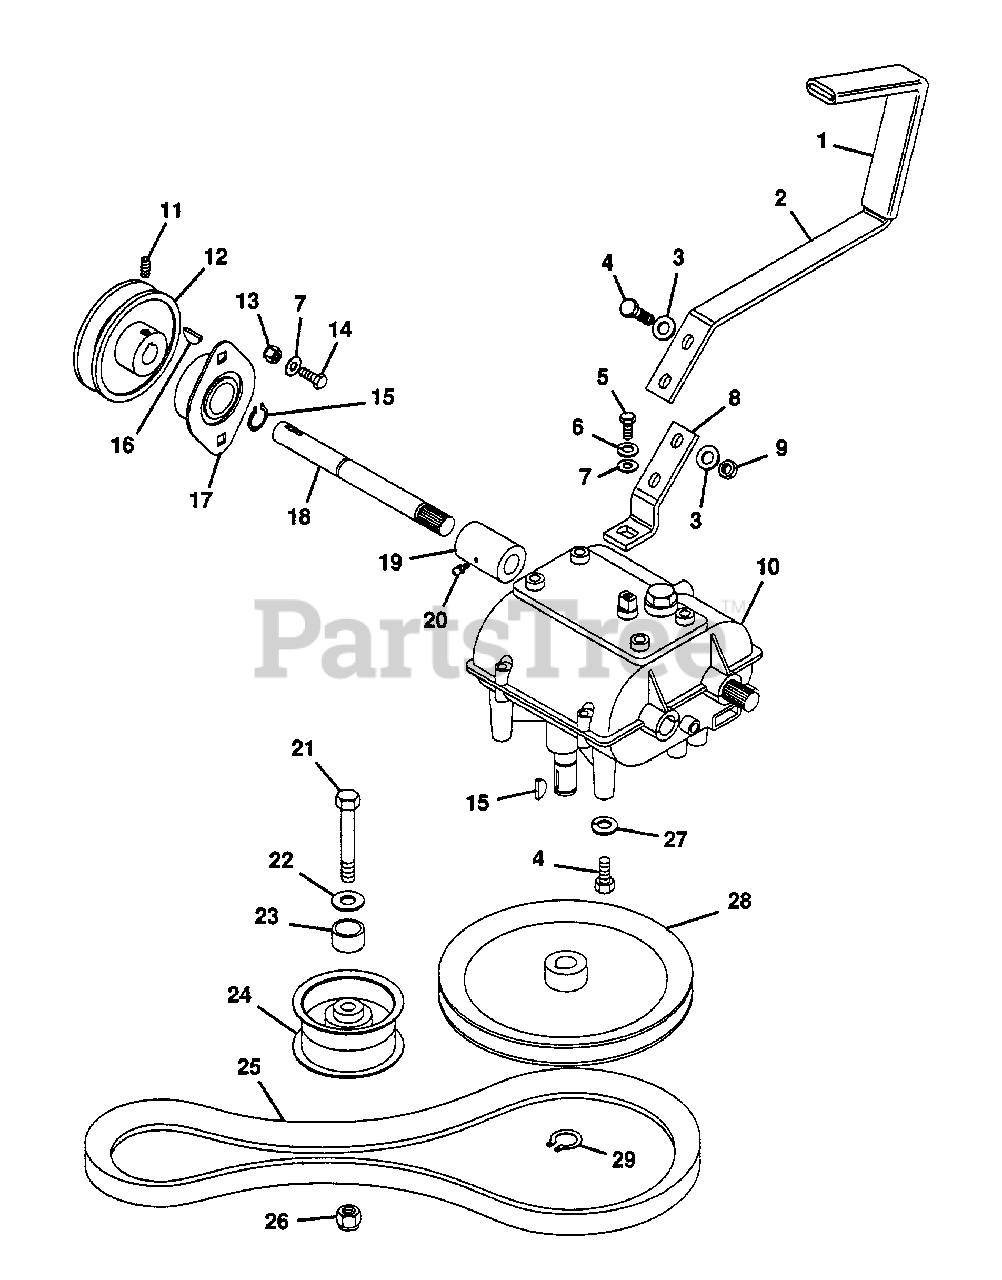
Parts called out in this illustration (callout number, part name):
1	GRIP
2	LEVER, TRANSMISSION SHIFT
3	WASHER, FLAT .344X.688X.065
4	BOLT, HEX 5/16-18X1.00
5	BOLT, HEX 1/4-28X.50
6	WASHER, LOCK 1/4
7	WASHER, FLAT .281X.625X.065
8	ARM, TRANS. SHIFT
9	NUT, LOCK 5/16-18
10	TRANSMISSION, 5-SPEED PRO 32
11	SCREW, SET 1/4-20X.375
12	SHEAVE, TRANSMISSION SHAFT EXT.
13	NUT, LOCK 1/4-20
14	BOLT, HEX 1/4-20X.750
15	RING, RETAINING
16	KEY, WOODRUFF .187X.75 HARD #9
17	BEARING, FLANGED
18	SHAFT, TRANSMISSION EXTENSION
19	COUPLER, TRANSMISSION SHAFT
20	FITTING, LUBE 1/4-28
21	BOLT, HEX 3/8-16X2.25
22	WASHER, FLAT .406X.812X.065
23	SPACER, .625X.385X.42
24	PULLEY, IDLER (PRO 32)
25	BELT-V, ENGINE TO TRANSMISSION
26	NUT, LOCK 3/8-16
27	WASHER, LOCK 5/16 REG.
28	SHEAVE, TRANSMISSION
29	RING, RETAINING
